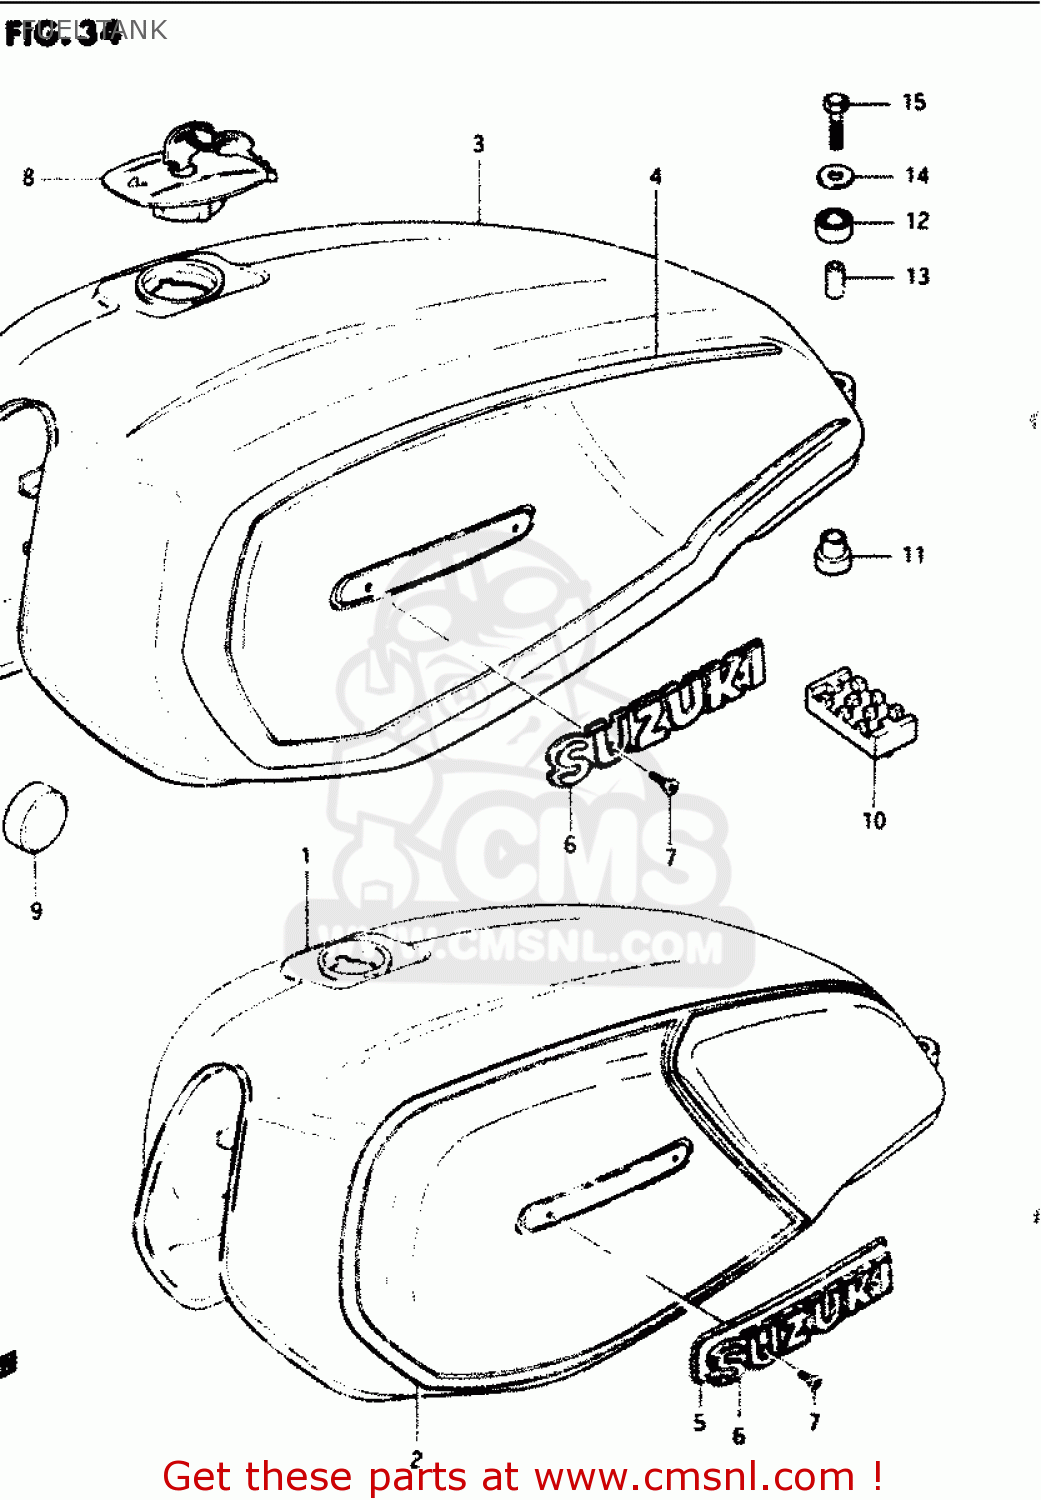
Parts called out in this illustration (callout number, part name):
1	TANK, FUEL
2	TAPE SET, FUEL TANK
3	TANK, FUEL
4	TAPE SET
5	CUSHION, EMBLEM
6	EMBLEM,FUEL TANK
7	SCREW 3X6
8	CAP SET,FUEL TANK
9	CUSHION
10	CUSHION,FUEL TANK
11	CUSHION
12	CUSHION
13	SPACER (6.4X9X21.5)
14	WASHER (6.5X24X1.6)
15	BOLT
